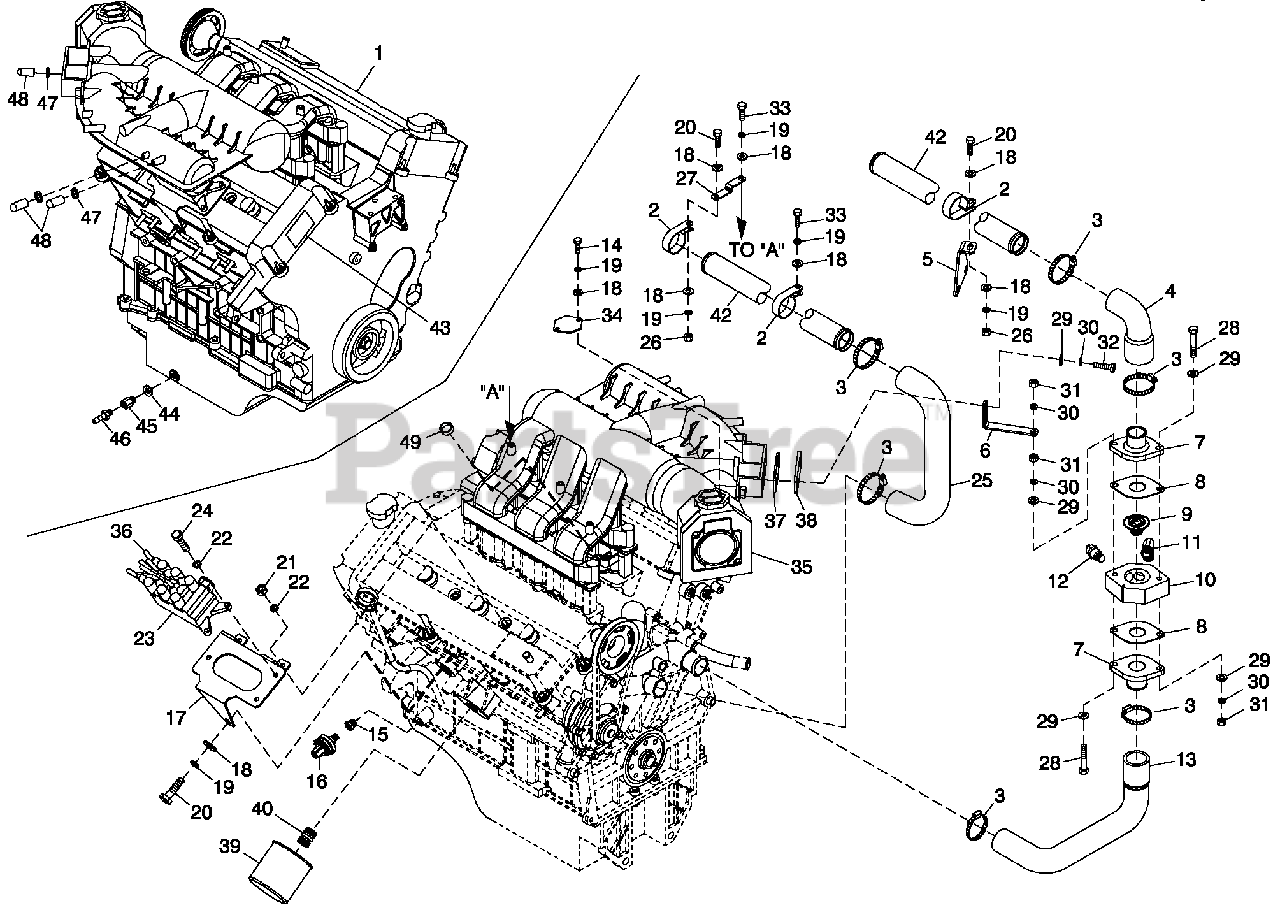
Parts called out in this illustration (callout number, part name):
1	ENGINE, 3.0LG3(FWD)
2	CLAMP VINYL 1.5 X.281Z
3	CLAMP HOSE #28 1.32-2.25
4	HOSEUPPR RAD REAR
5	BRACKET, UPPER RADIATOR HOSE
6	BRACKET, THERMOSTAT HOUSING
7	ADAPTER THERMOSTAT
8	GASKET THERMOSTAT
9	THERMOSTAT 195 DEG
10	MACHINING,THERMOSTAT ADPTR
11	BARBED EL 90 1/2 NPT X 3/4 HOSE
12	SWITCH HI-TEMP 245D X 3/8 NPT
13	HOSE LOWER RADIATOR REAR G3
14	SCREW HHC M6-1.0X 16 C8.8
15	BSHG RDCR HEX 3/8 TO 1/8 GALV
16	SWITCH OIL PRESSURE 10PSI2P
17	BRACKET,COIL
18	WASHER FLAT 1/4-M6 ZINC
19	WASHER LOCK M6-1/4
20	SCREW HHC M6-1.0X 20 C8.8
21	NUT HEX M5-0.8 G8 CLEAR ZINC
22	WASHER LOCK M5
23	COIL IGNITION
24	SCREW HHC M5-0.8X 25 G8.8
25	HOSE,LOWR RAD REAR
26	NUT HEX M6 X 1.0 G8 YEL CHR
27	BRACKET, LOWER RADIATOR HOSE
28	SCREW HHC M8-1.25X 80 C8.8
29	WASHER FLAT 5/16-M8 ZINC
30	WASHER LOCK M8-5/16
31	NUT HEX M8-1.25 G8 CLEAR ZINC
32	SCREW HHC M8-1.25X 20 C8.8
33	SCREW HHC M6-1.0X 12 G8.8
34	COVER IAC ACTUATOR
35	MANIFOLD INTAKE UPPER
36	SPARKPLUG WIRES, 3.0L G3
37	EGR GASKET
38	COVEREGR
39	OIL FILTER
40	ADAPTER OIL FILTER 3.0L
42	TUBE UPPER COOLANT
43	DECAL EMISSION CTRL INFO 3.0L
44	WASHER NYLON .50 X .87 X .06
45	ADAPTER M12-1.75X 3/8 NPT
46	BARBED STR 3/8 NPT X 3/8
47	CLAMP HOSE #5.5.62-.62
48	CAP VINYL 3/8"IDX1"DP BLK
49	PLUG EXPANSION 14 OD
